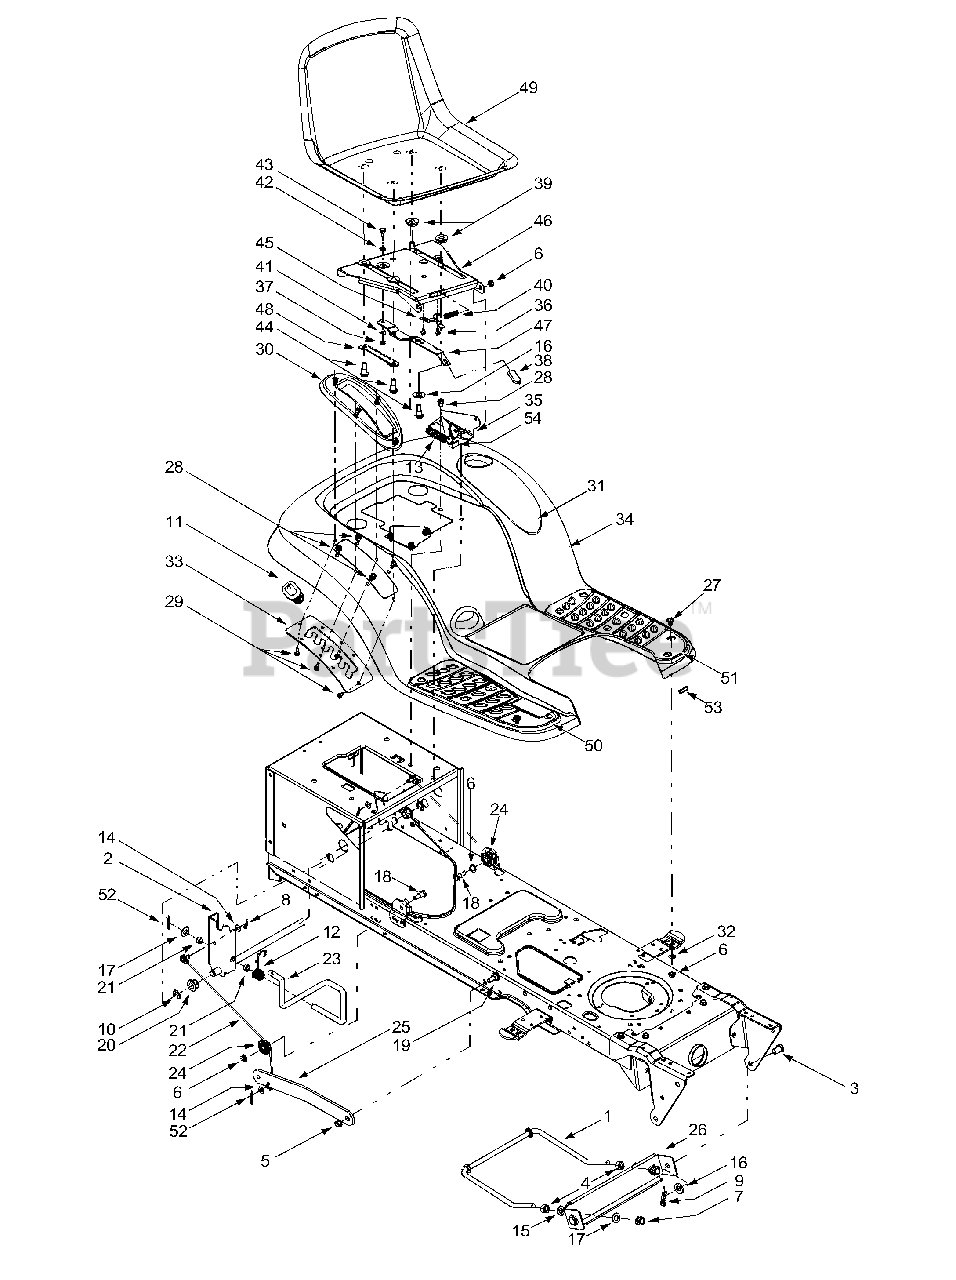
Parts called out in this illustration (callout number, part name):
3	Clevis Pin, .5 x .78
4	Hex Nut, 1/2-13
5	Flange Lock Nut, 3/8-16
6	Flange Lock Nut, 5/16-18
7	Hex Nut, 1/2-13
8	Internal Cotter Pin
9	Internal Cotter Pin
11	Handle Grip
12	Torsion Spring
13	Extension Spring, .872 x 3.4
14	Flat Washer, 5/16
15	Lock Washer, 1/2
16	Flat Washer, .31 x 1.062 x .134
17	Flat Washer, .51 x 1.12 x .06
18	Hex Cap Screw, 5/16-18 x .62
19	Shoulder Screw, 3/8-16
20	Hex Flange Bearing
21	Snap Flange Bearing
22	Lift Cable, 16.16
23	Lift Handle
24	Roller Pulley
27	Carriage Bolt, 5/16 x .62
28	Self-tapping Screw, 5/16-18 x .625
29	Self-tapping Screw, 1/4-15 x .75
30	Lift Lever Cover
31	Cover w/ Cup Holder
32	Flat Washer, .349 x 1.0 x .063
36	Screw, #10-16 x .375
37	Hex Flange Lock Nut, 1/4-20
38	Seat Adjuster Grip
40	Compression Spring, .41 x 1.5
41	Spring Washer, .265 x .562 x .025
42	Flat Washer, .344 x .62 x .03
43	Shoulder Screw, .340 x .285,1/4-20
44	Shoulder Screw, .50 x .50, 3/8-16
45	Seat Stop
48	Seat Adjustment Selector
49	Medium Back Seat, Yellow
50	RH Foot Pad
51	LH Foot Pad
52	Cotter Pin
53	Trim Strip
54	Seat Lift Bracket
